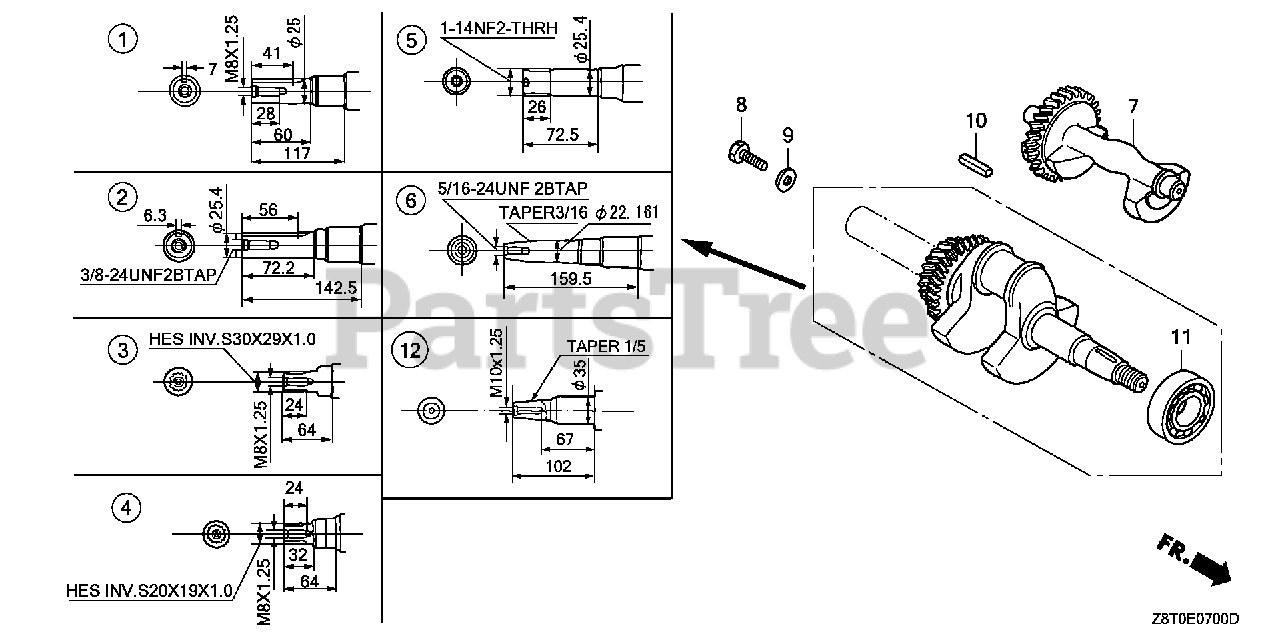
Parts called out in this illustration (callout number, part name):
2	CRANKSHAFT
7	WEIGHT, BALANCER
10	KEY (6.3X6.3X43)
11	BEARING, RADIAL BALL (6207SH)
